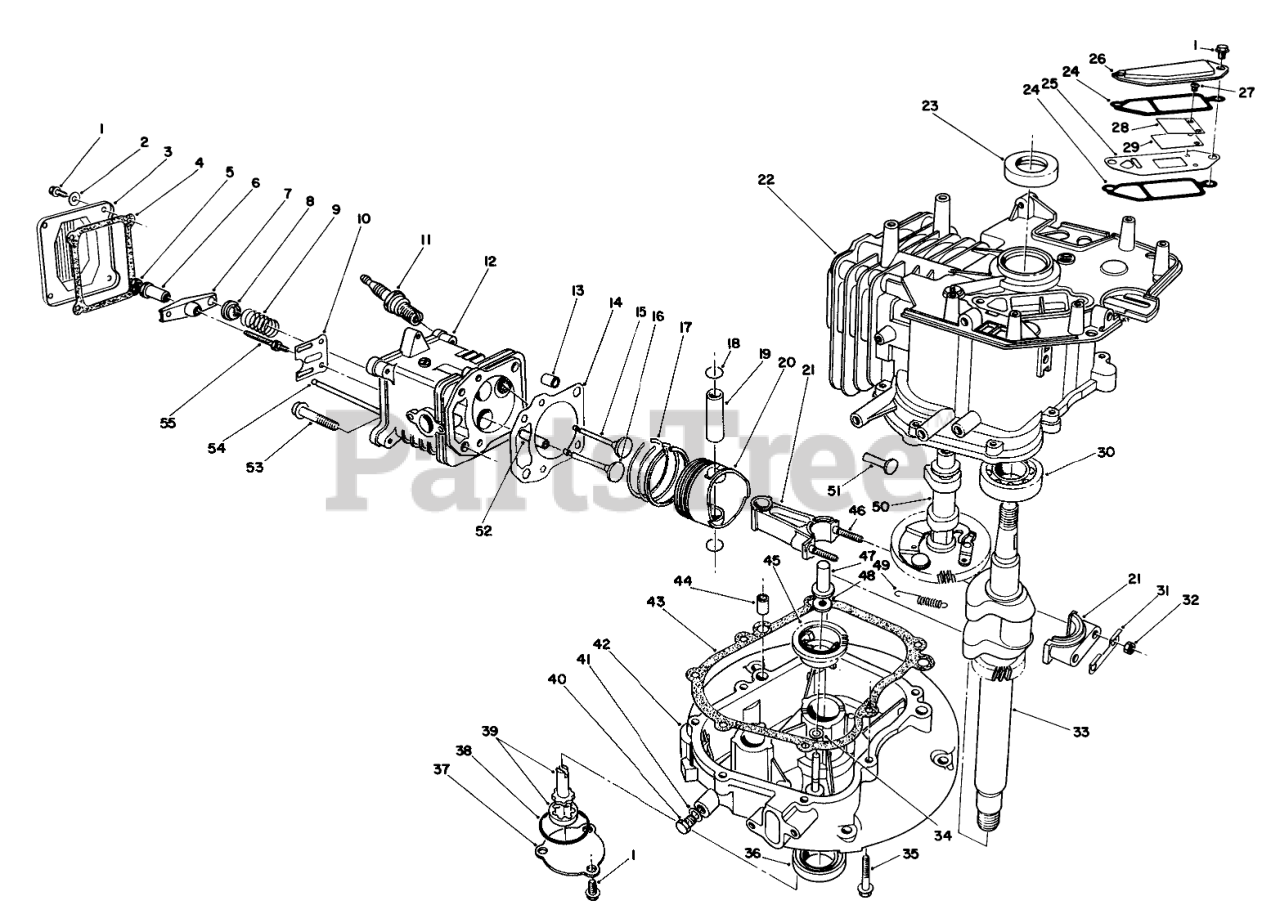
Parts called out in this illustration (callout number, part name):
2	WASHER
3	COVER
4	GASKET
6	PIVOT
8	RETAINER
9	SPRING
10	GUIDE
11	SPARK PLUG
14	Gasket-Cylinder Head
15	VALVE-INTAKE
16	VALVE-EXHAUST
17	RING SET
18	CIRCLIP
20	PISTON
21	CONN ROD
22	ENGINE BLOCK
24	GASKET
25	Plate-Breather
26	COVER
27	Screw-Reed Valve
28	Retainer-Reed Valve
29	Valve-Reed
30	BEARING
31	Plate-Lock
33	CRANKSHAFT
34	WASHER
37	COVER
38	O-RING
39	OIL PUMP
40	Plug-Oil Drain
41	GASKET
42	Crankcase
43	GASKET
45	GOVERNOR FLYWEIGHT ASM
47	PLUNGER
48	WASHER
49	SPRING
50	CAMSHAFT
51	TAPPET
52	GUIDE
